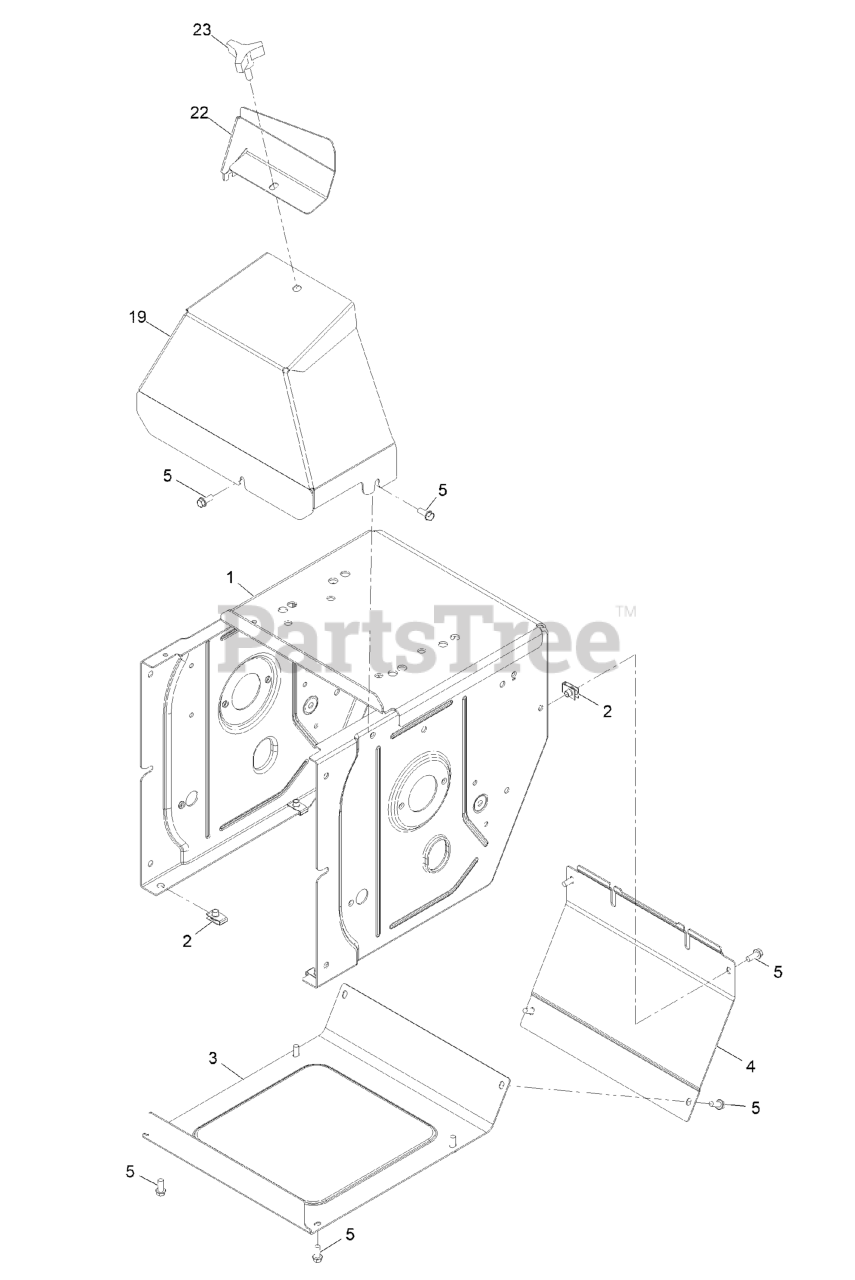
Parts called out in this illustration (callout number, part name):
1	FRAME, TRACTION
3	COVER-BOTTOM
4	COVER-REAR
5	SCREW-HWH
19	COVER - BELT
22	SHIELD-ICE, KC CH270
